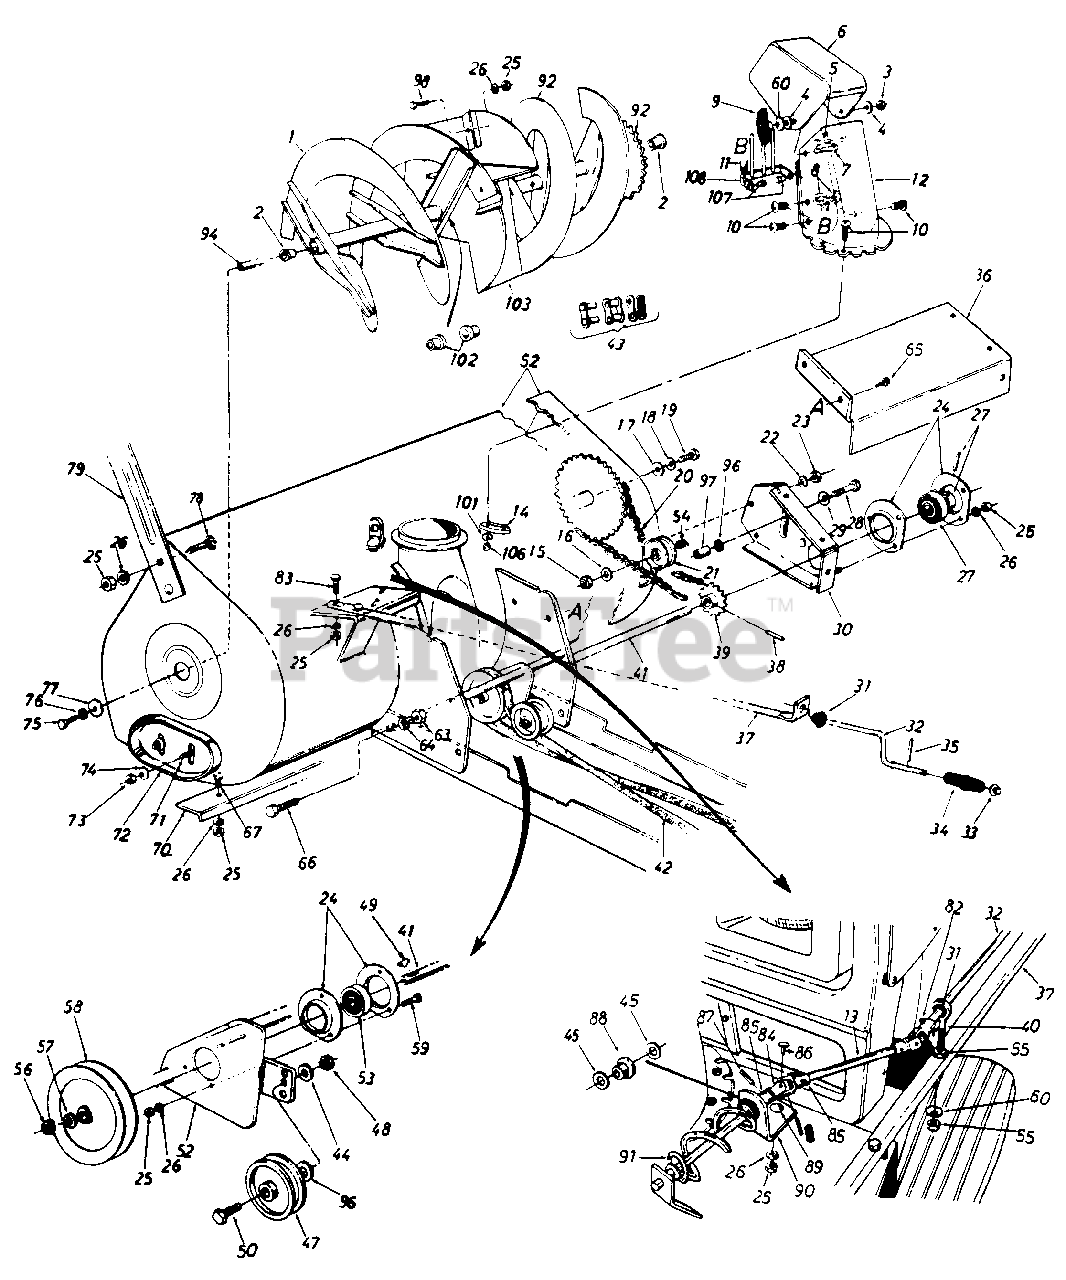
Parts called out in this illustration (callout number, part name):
3	Hex Cent. L.-Nut 5/16-18 Thd.
4	Fl.-Wash. .344' I.D.
5	Truss Mach. Scr. 5/16-18 x .75" 4.
6	Upper Chute
7	Carriage Bolt 5/16-18 x 1.0" Lg.
8	Hex l-Nut 1/4-20 Thd.
9	Hand Knob
10	Truss Mach. Scr. 1/4-20 x .75" Lg.
11	Ext. Spring
12	Lower Chute
13	Chute Crank Extension Rod
14	Chute Flange Keeper
15	L.-Nut 3/8-16 Thd.
16	Fl.-Wash.
17	Fl.-Wash.
18	Belleville Wash.
19	Hex Bolt 1/2-13 x 1.00" Lg.
20	#420 Chain 1/2" Pitch x 77 Links
21	Plastic Idler 2.00" O.D.
22	L.-Wash. 1/4" I.D.
23	Hex Nut 1/4-20 Thd.
24	Bearing Housing
25	Hex Nut 5/16-18 Thd.
26	L.-Wash. 5/16" I.D.
27	Self-Aligning Bearing
28	Hex Bolt 3/8-16 x 1.75" Lg.
29	Belleville Wash. 3/8" I.D.
32	Chute Crank .375 Dia. x 34.5" Lg.
33	Push Nut 3/8" Rod
34	Knob (Black)
35	Roll Pin
39	14 Teeth Sprocket Ass'y.
40	Eyabolt 5/16-18 x 3.0" Lg.
41	Drive Shaft
42	"V"-Belt
43	Master Link for #420 Chain
44	L.-Wash. 3/8" I.D.
45	Fl.-Wash..385 I.D. x .62" OD.
47	Fl.-Idler with Flanges
48	Hex Jam L.-Nut 3/8-16 Thd.
49	J'61 Hi-Pro Ke 3/16 x 5/8 Dia.
50	Hex Bolt 3/8-16 x 1.75" Lg.
52	Spiral Housing Ass'y.
53	Self-Aligning Bearing
54	Sleeve Bearing .50" I.D.
55	Hex Nut 5/16-18 Thd.
56	Hex Nut 3/4-10 Thd.
57	L.-Wash. 3/4" I.D.
58	"V"-Pulley .750" I.D. x 6.00" O.D.
59	Hex Sems Bolt 5/16-18 x .75" Lg.
60	Bell.-Wash. 345" I.D. x .88" O.D.
63	Hex Nut 1/2-13 Thd.'
64	L.Wash. 1/2" I.D.
65	Hex Wash. Hd. Tap Scr. 1/4-20 x .50" Lg.
66	Hex Bolt 1/2-13 x 2.75" Lg.
67	Carriage Bolt 5/16-18 x .75"
72	Skid Shoe
73	Hex Jam Nut 3/8-16 Thd.
74	Belleville Wash. 3/8" I.D.
75	Hex Bolt 1/2-13 x 1.00" Lg
76	Belleville Wash. 1/2" I.D.
77	Fl.-Wash.
78	Carriage Bolt 5/16-19 x .62" Lg.
82	Cotter Pin
83	Hex Bolt 5/16-18 x 1.50" Lg.
84	Joint Block
85	Joint Bracket Ass'y.
86	Oval Head Rivet
87	Spring Pin Roll 1/8" Dia. x 75" Lg.
88	Nylon Bushing
89	Carriage Bolt 5/16-18 x .75" Lg.
90	Chute Crank Bracket
91	Chute Crank Ass'y.
96	Flat Washer
97	Idler Spacer
98	Carriage Bolt 5/16-18 x .75" Lg.
101	Fl.-Wash. 1/4" I.D.
102	Plastic Bushing
107	Shld. Nut 1/4-20 Thd.
05139A-0637	BLADE-GUIDE (DRIFT - POWDER BLACK (0637)
05139A-0638	BLADE-GUIDE (DRIFT - MTD/TROY-BILT RED (0638)
05139A-0662	BLADE-GUIDE (DRIFT - OYSTER GRAY (0662)
05139A-0665	BLADE-GUIDE (DRIFT - YARDMAN GREEN (0665)
05139A-0674	BLADE-GUIDE (DRIFT - YARDMAN YELLOW (0674)
05139A-0716	BLADE-GUIDE (DRIFT - CUB YELLOW-99 (0716)
